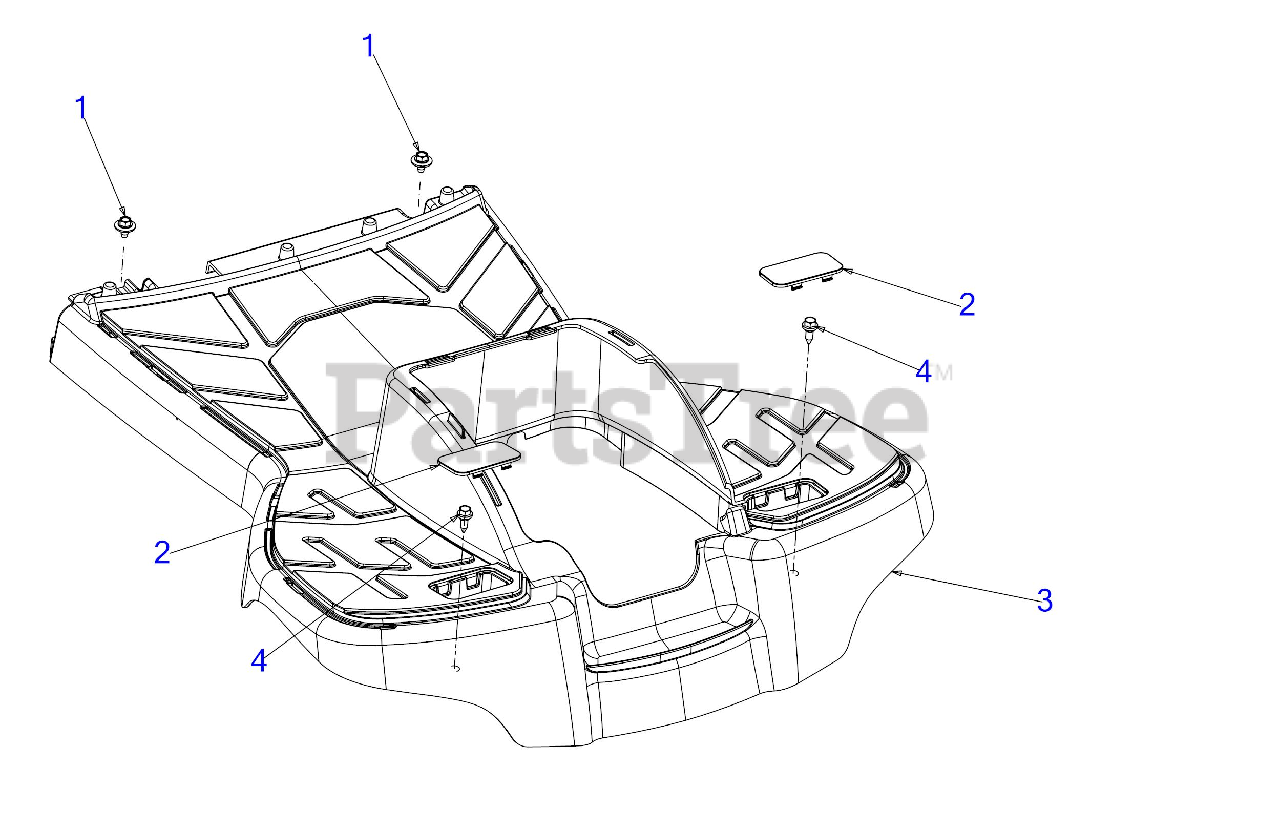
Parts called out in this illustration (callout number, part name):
1	SCREW 1/4-20 x .50
2	RUNNING BOARD PLUG
3	RUNNING BOARD
4	SHOULDER SCREW
